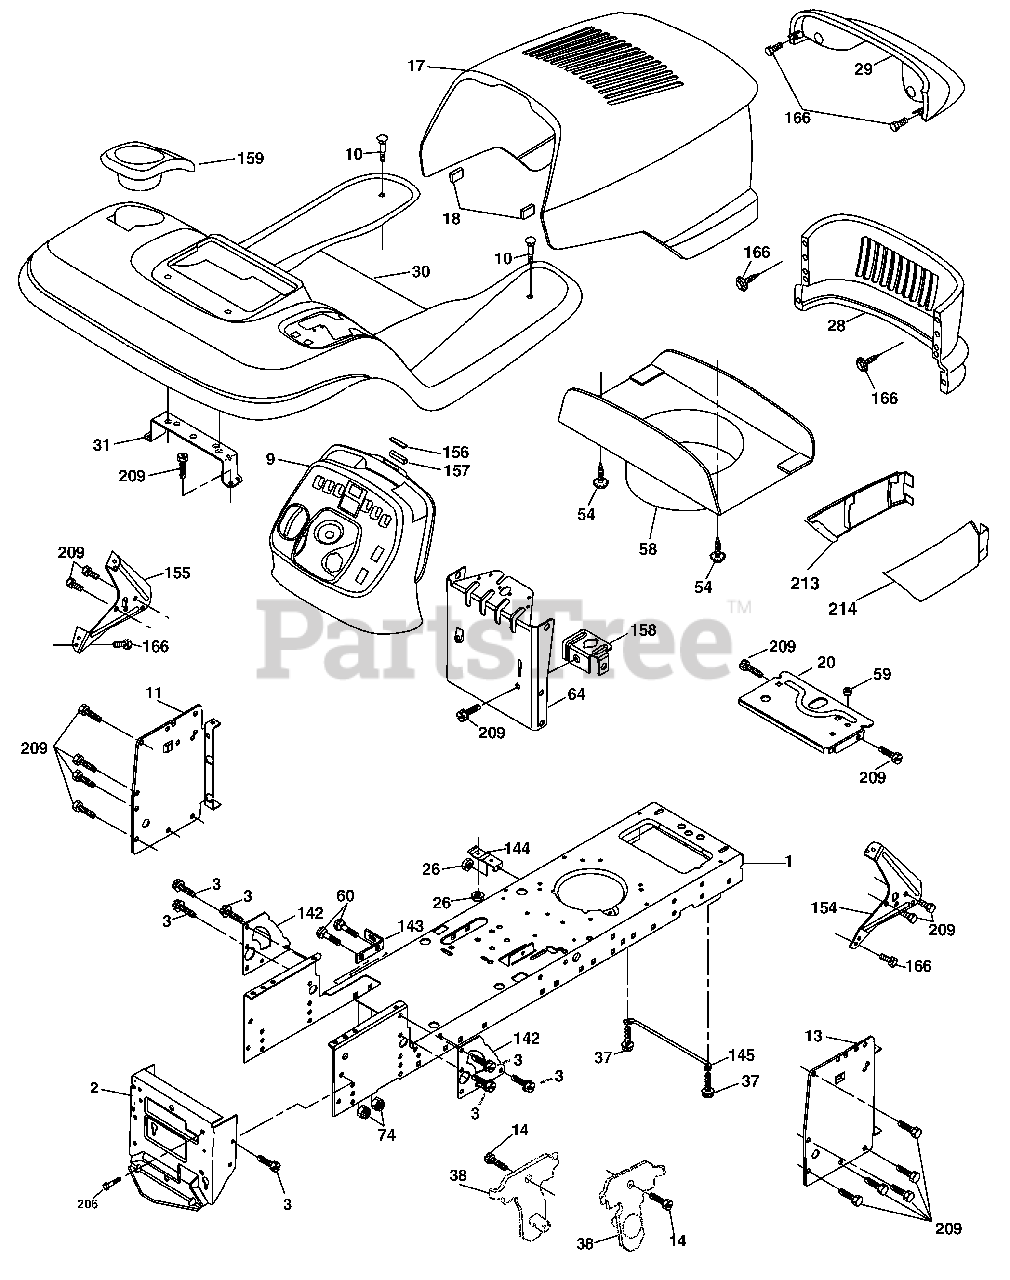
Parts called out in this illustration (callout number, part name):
1	Chassis
2	Drawbar
3	Screw 3/8-16 x 3/4
9	Dash
10	Bolt 3/8-16 x 1
11	Panel Dash Lh
13	Panel Dash Rh
14	Screw Thdrol 3/8-16 x 1/2
17	Hood
18	Extrusion Bumper
20	Plate Battery
26	Nut Lock Hex W/Ins 3/8-16 Unc
28	Grille
29	Light Box Asm W/Lens
31	Bracket Fender
37	Screw Thdrol 6/16-18 x 1/2 TYT
38	Bracket, Asm. Pivot Mower Rear
54	Screw Hex Wshd 8-18 x 7/8
58	Duct Hood
59	Bushing Snap
60	Bolt Rd Hd Sqnk 3/8-16 Unc x 3/4
64	Dash Lower
74	Nut Crownlock 3/8-16 Unc
142	Plate Reinforcement STLT
143	Bracket Swaybar Chassis
144	Bracket Footrest
145	Rod Pivot Chassis/Hood
154	Bracket Dash Rh
155	Bracket Dash Lh
156	Striker Plate
157	Magnet Stealth
158	Bracket Parking Brake
159	Cupholder
166	Screw Hw Hd Hi-Lo #13-16 x 3/4
206	Bolt Shoulder 5/16-18
209	Screw Hexwsh Thdrol 3/8-16 x 3/4
213	Skirt Grille Lh
214	Skirt Grille Rh
